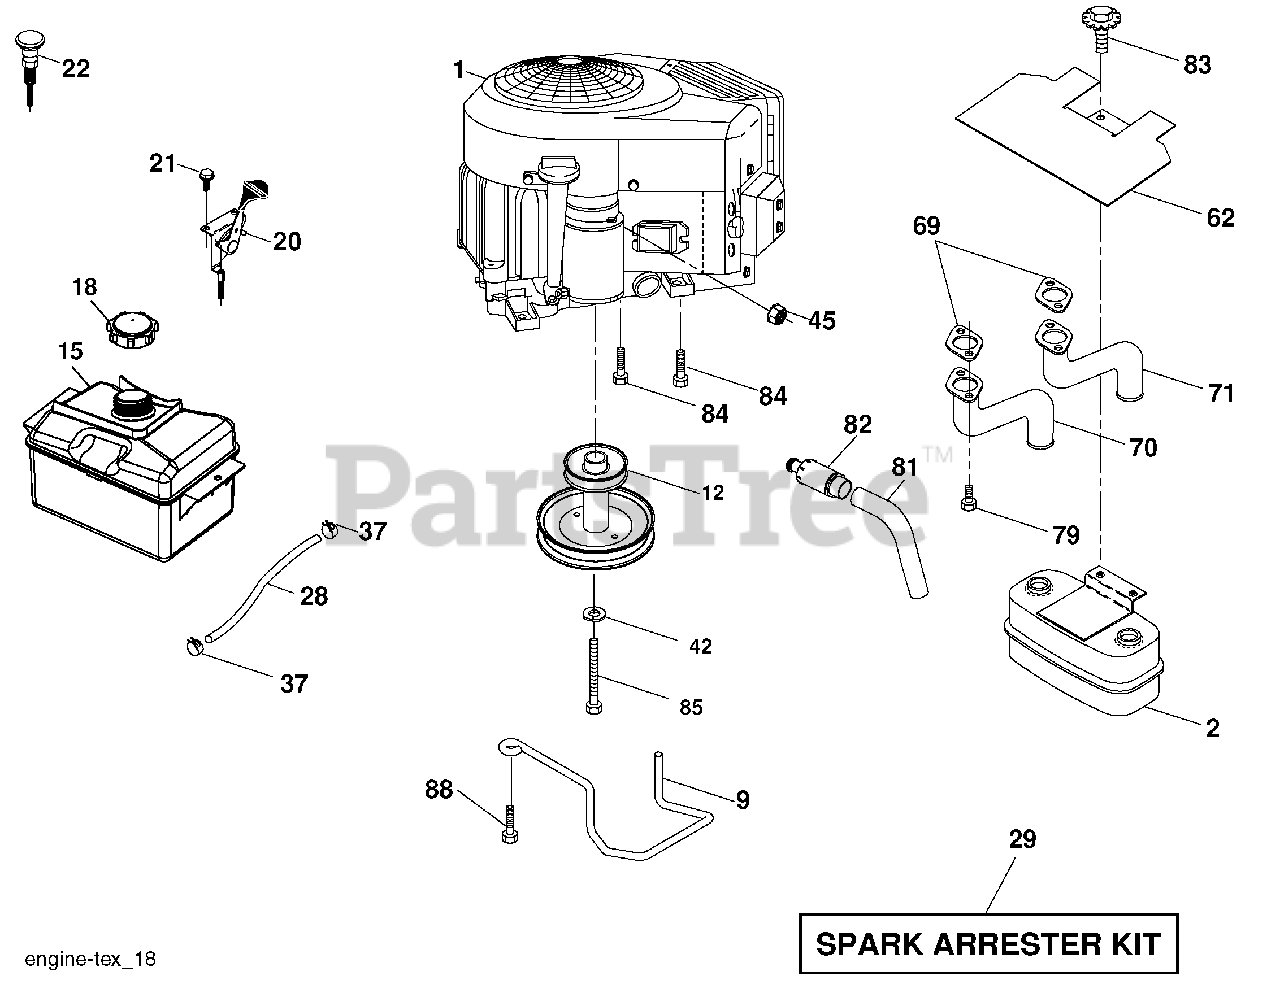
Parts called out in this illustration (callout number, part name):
2	Muffler
9	Keeper Belt Engine
12	Pulley Engine
15	Tank Fuel
18	Cap Asm
20	Control Throttle/Choke
21	Screw 10 x 3/4 Single Lead-Hex
22	Control Choke
28	Fuel Line
29	Spark Arrester Kit
37	Clamp Hose
42	Washer Lock 7/16
45	Nut Keps Hex 1/4-20 unc
62	Shield Heat Muffl er
69	Gasket
70	Exhaust Tube LH
71	Exhaust Tube RH
79	Screw Socket Head 5/16-18 x 1
81	Tube Drain Oil Easy
82	Plug Drain Oil
83	Bolt 5/16-18 UNC x 3/4
84	Screw 3/8-16 x 1-1/4
85	Bolt Hex 7/16-20 x 4 x Gr. 5-1.5
88	Screw 3/8-16 x 1
